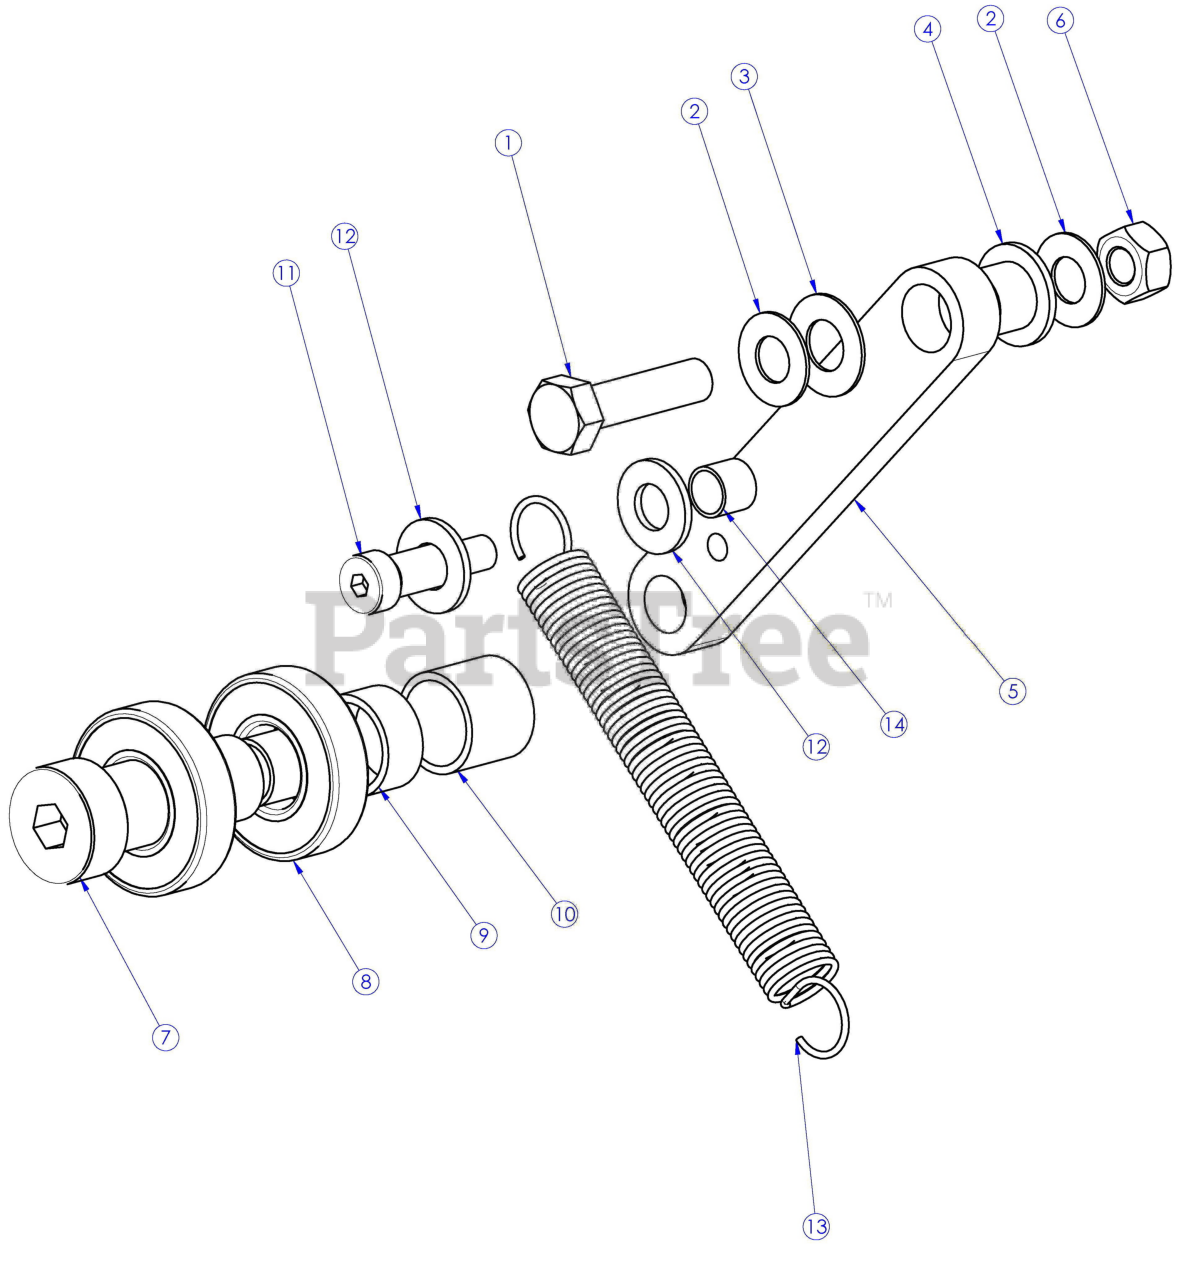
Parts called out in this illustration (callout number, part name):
1	HHB 5/16-24 X 1.25
2	Washer, 5/16" Flat S.S.
3	Washer, 3/8" Delrin
4	Flanged Bearing
5	Arm, Belt Tensioner
6	Nut, 5/16-24 Hex, Gr5 Zinc
7	Shsb, 5/8 X 1 1/2
8	Bearing, .625 Id, R10-2Rs
9	Spacer, .625"Id X .350"L Alum.
10	Spacer, .625"Id X .630"L Alum
11	Shsb, 5/16 X 5/8
12	Washer, 5/16" Flat Sae Cad
13	Spring, Extension
14	Spacer, .313"Id X .315"L G.A.
